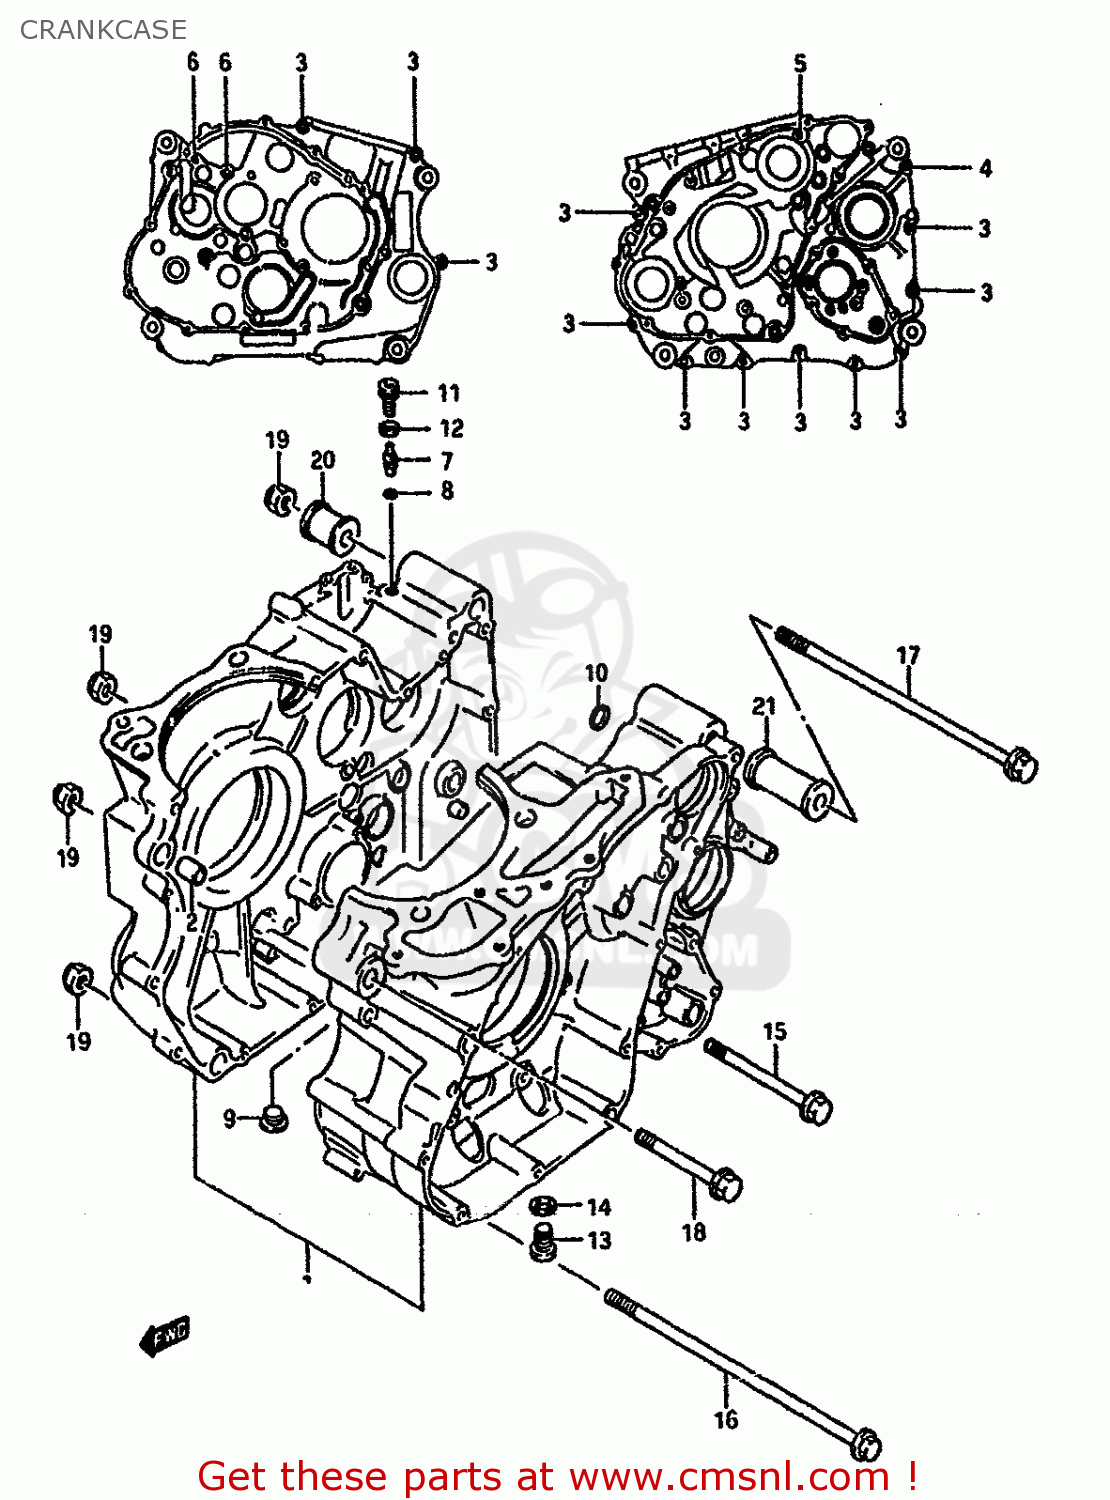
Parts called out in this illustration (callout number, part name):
1	CRANKCASE SET
2	PIN
3	BOLT
4	BOLT
5	BOLT
6	BOLT
7	JET(12)
8	O RING(D:1.2,ID:4)
9	PLUG
10	O RING(D:1.9,ID:11)
11	BOLT,LOWER
12	GASKET 8.2X14X1 (NAS)
13	BOLT
14	GASKET(12.1X16.2X3.7) (NAS)
15	BOLT
16	BOLT (10X215)
17	BOLT
18	BOLT 10X70
19	NUT
20	SPACER,ENGINE MOUNT
21	SPACER,ENG MTG,R(L:60)
